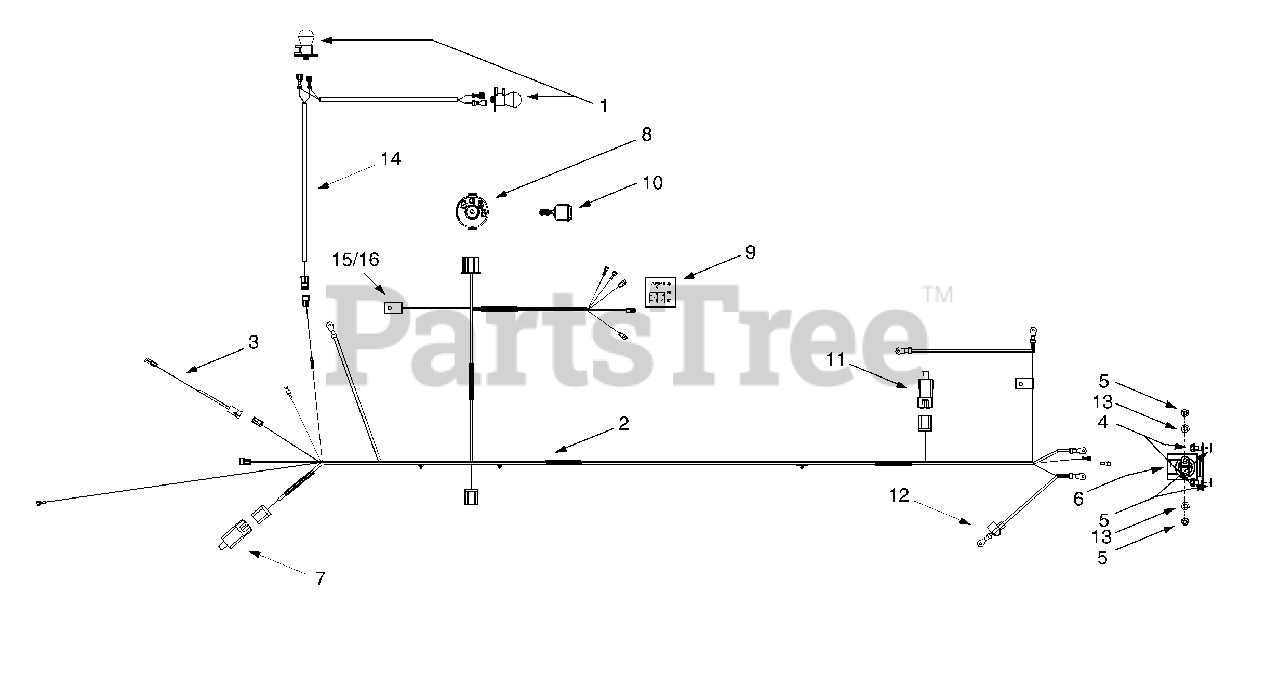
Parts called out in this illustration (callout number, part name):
1	Bulb/Socket Headlight Assembly
2	Wiring Harness w/o Ref. 14
3	Harness Adapter, #18 x 5
4	Self-tapping Screw, 1/4-20 x .5
5	Hex Nut, 1/4-20
6	Solenoid, 12-volt, 100 Amp
7	Snap Mount Safety Interlock Switch (Brake)
8	Ignition Switch
9	Systems Indicator Monitor
10	Ignition Key w/ plastic cover
11	Safety Plunger Switch (Seat)
12	Positive Terminal Cover (Boot)
13	Lock Washer, 1/4
14	Headlight Harness
15	Fuse Holder
16	20-amp Fuse
